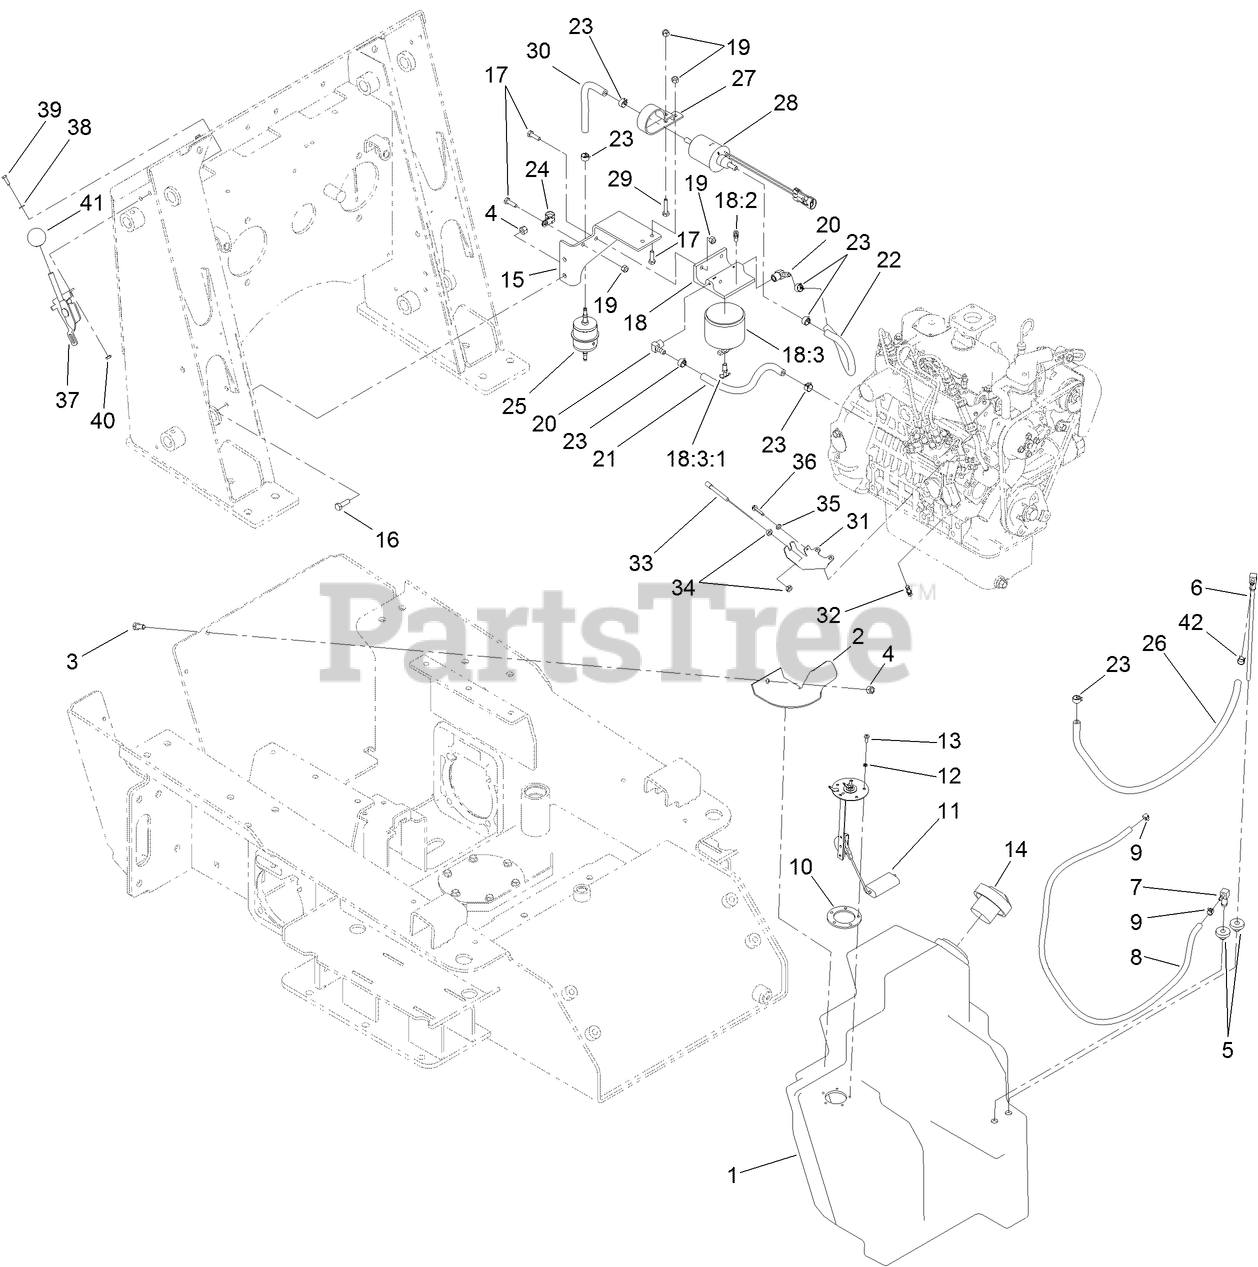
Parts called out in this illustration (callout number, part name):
1	TANK-FUEL
2	CLAMP-TANK, FUEL
3	SCREW-HH
4	NUT-LOCK, NI
5	BUSHING
6	PIPE-STAND
7	FITTING-ELBOW, 90 DEG
8	HOSE-FUEL
9	CLAMP-HOSE
10	GASKET-SENDER, FUEL
11	SENDER-FUEL
12	WASHER-LOCK
13	SCREW-PPH
14	CAP-DIESEL
15	BRACKET-PUMP, FUEL
16	SCREW-HH
17	SCREW-HH
18	FILTER HEAD ASM
18:2	VENT-AIR
18:3	ELEMENT-SPIN ON
18:3:1	VALVE-DRAIN
19	NUT-LOCK, NI
20	FITTING-HYD, 90
21	HOSE-FUEL
22	HOSE-FUEL
23	CLAMP-HOSE
24	CLAMP-R
25	FILTER-INLINE
26	HOSE-FUEL
27	BRACKET-PUMP, FUEL
28	PUMP-FUEL
29	SCREW-HH
30	HOSE-FUEL
31	BRACKET-SUPPORT, THROTTLE
32	SWIVEL-STOP, CABLE
33	CABLE-THROTTLE
34	NUT-JAM
35	NUT-HEX
36	SCREW-HWHTF
37	LEVER-CONTROL
38	WASHER-FLAT
40	NUT-KEPS
42	CLAMP-HOSE
